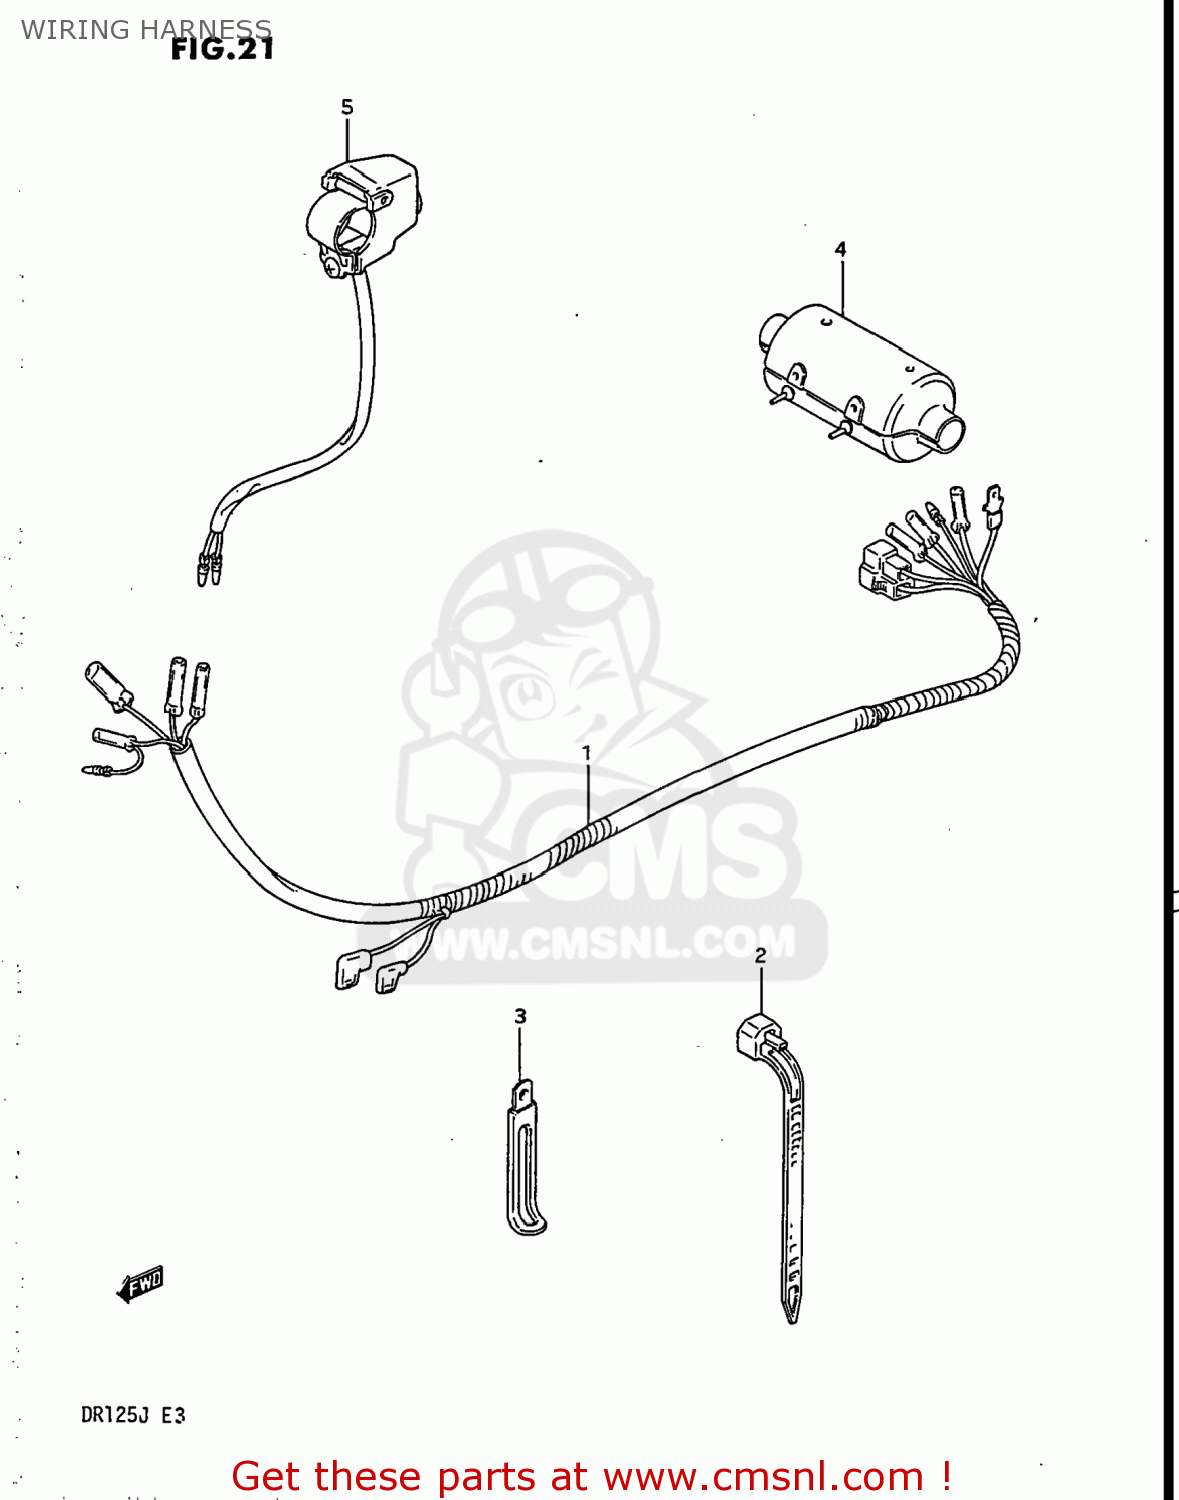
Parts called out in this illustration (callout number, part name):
1	HARNESS,WIRING
2	CLAMP(L:125)
3	CLAMP
4	BOOT,WIRING HARNESS
5	SWITCH ASSY,ENGINE STOP
